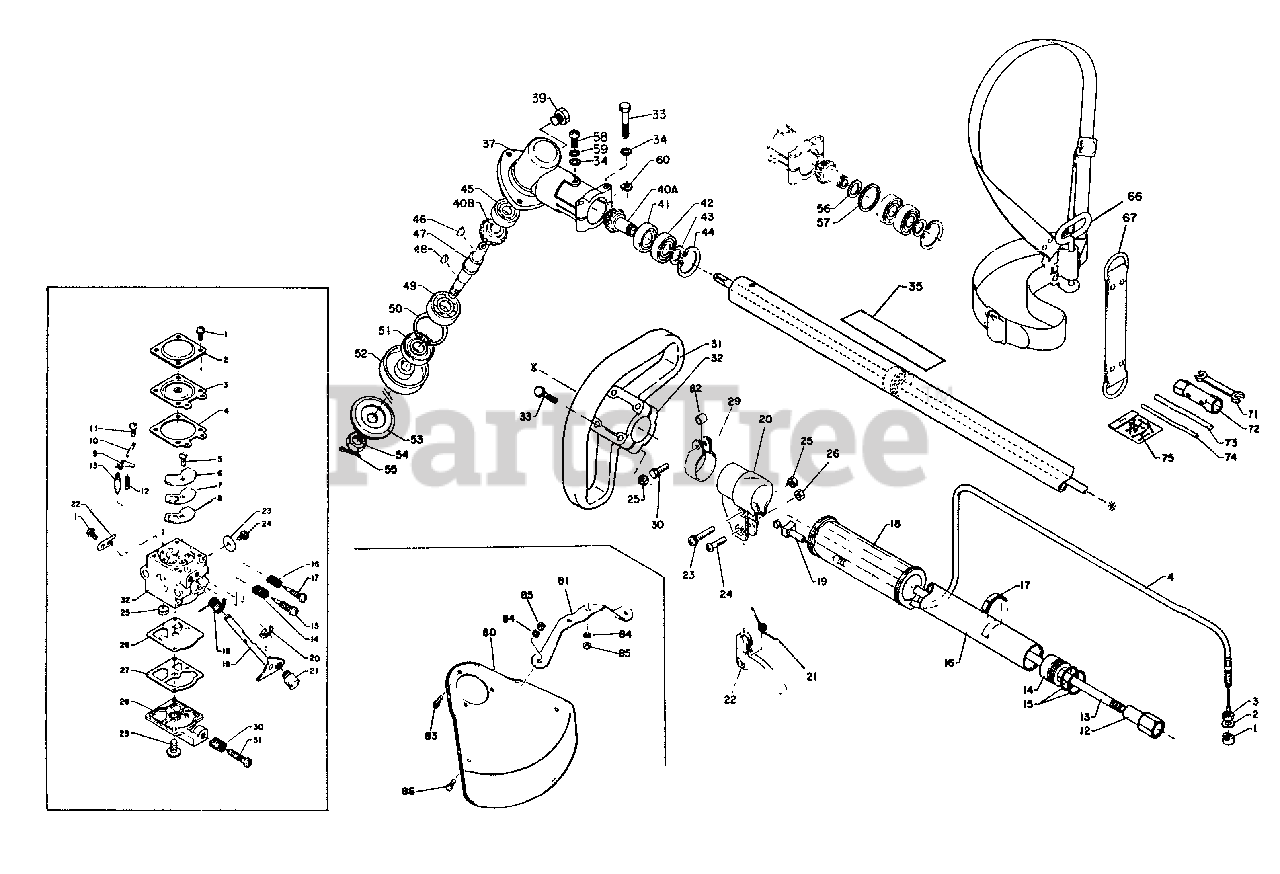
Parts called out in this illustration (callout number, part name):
1	Lock Nut
2	Washer 6
2	Cover, Metering Diaphragm
3	Diaphragm, Metering
4	Throttle Cable
4	Gasker, Metering Diaphragm
5	Screw, Circuit Plate
6	Plate, Circuit
7	Diaphragm, Circuit Plate
8	Gasker, Circuit Plate
9	Lever, Metering
10	Pin, Metering Lever
11	Screw, Metering Lever Pin
12	Spring, Metering Lever
13	Shaft, Drive
13	Valve, Inlet Needle
14	Bush
14	Spring, h.s. Needle
15	o-Ring 22
15	Needle, High Speed
16	Housing, Ass'y, Drive Shaft
16	Spring, Idle Needle
17	Needle, Idle
18	Grip
18	Spring, Throttle Return
19	Shaft Ass'y, Throttle
20	Bracket, Throttle Trigger
20	Clip
21	Spring, Throttle Return
22	Throttle Trigger
22	Clip, Throttle Shaft
23	Screw 5 x 30
23	Valve, Throttle
24	Screw, Throttle Valve
25	Screen, Inlet
26	Lock Nut 5
26	Diaghragm, Fuel Pump
27	Gasker, Fuel Pump
28	Cover, Fuel Pump
29	Screw, Fuel Pump
30	Bolt 5 x 14
30	Spring, Idle Screw
31	Handle
31	Screw, Idle Adjustment
32	Bracket, Handle
33	Screw 5x35
33	Bolt 5 x 40
34	Washer 5
35	Decal, Caution
37	Housing, Gear
39	Bolt 8 x 8
40	Gear Set
41	Ball Bearing 6001
42	Ball Bearing 6001
43	Circlip 12
44	Circlip 28
45	Ball Bearing 6000
46	Woodruff Key
47	Shaft, P.T.O.
48	Woodruff Key
49	Ball Bearing 6201
50	Circlip 32
51	Oil Seal
52	Plate, Blade Fixing
53	Plate, Blade Fixing
54	Nut 10 l-h
55	Split Pin 2 x 22
58	Screw 5 x 10
59	Spring Washer 5
66	Shoulder Strap
67	Strap
71	Spanner 8 x 10
72	Box Wrench 17 x 19
73	Handle, Wrench
74	Locking Bar
75	10 Pcs Split Pin
80	Shield
81	Bracket
83	Screw 5 x 10
84	Spring Washer 5
86	Screw 5 x 8
